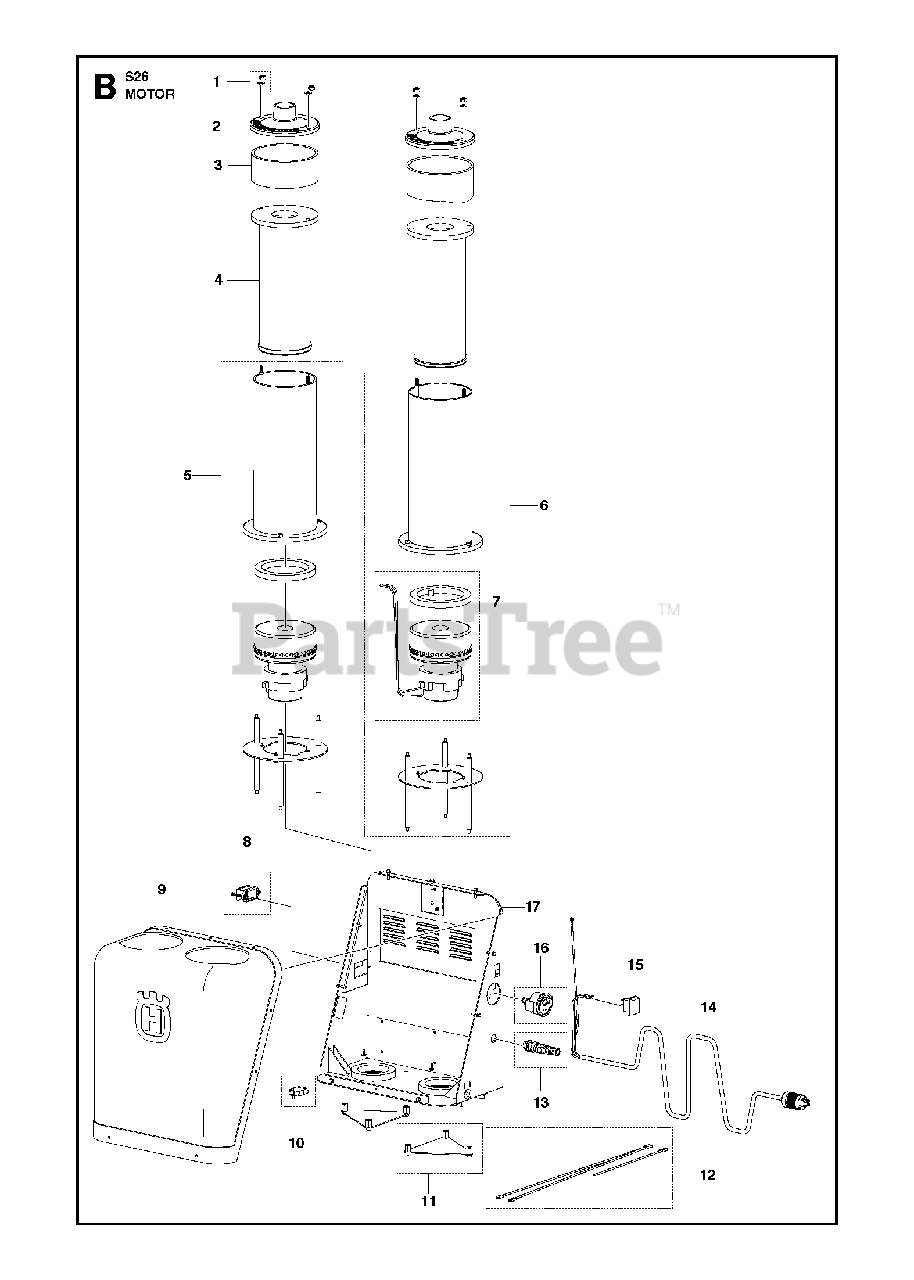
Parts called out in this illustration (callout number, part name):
5	MOTOR120V, TUBE KIT WITHOUT NIPPLE
5	MOTOR230V, TUBE KIT WITHOUT NIPPLE
6	MOTOR120V, TUBE KIT WITH NIPPLE
6	MOTOR230V, TUBE KIT WITH NIPPLE
